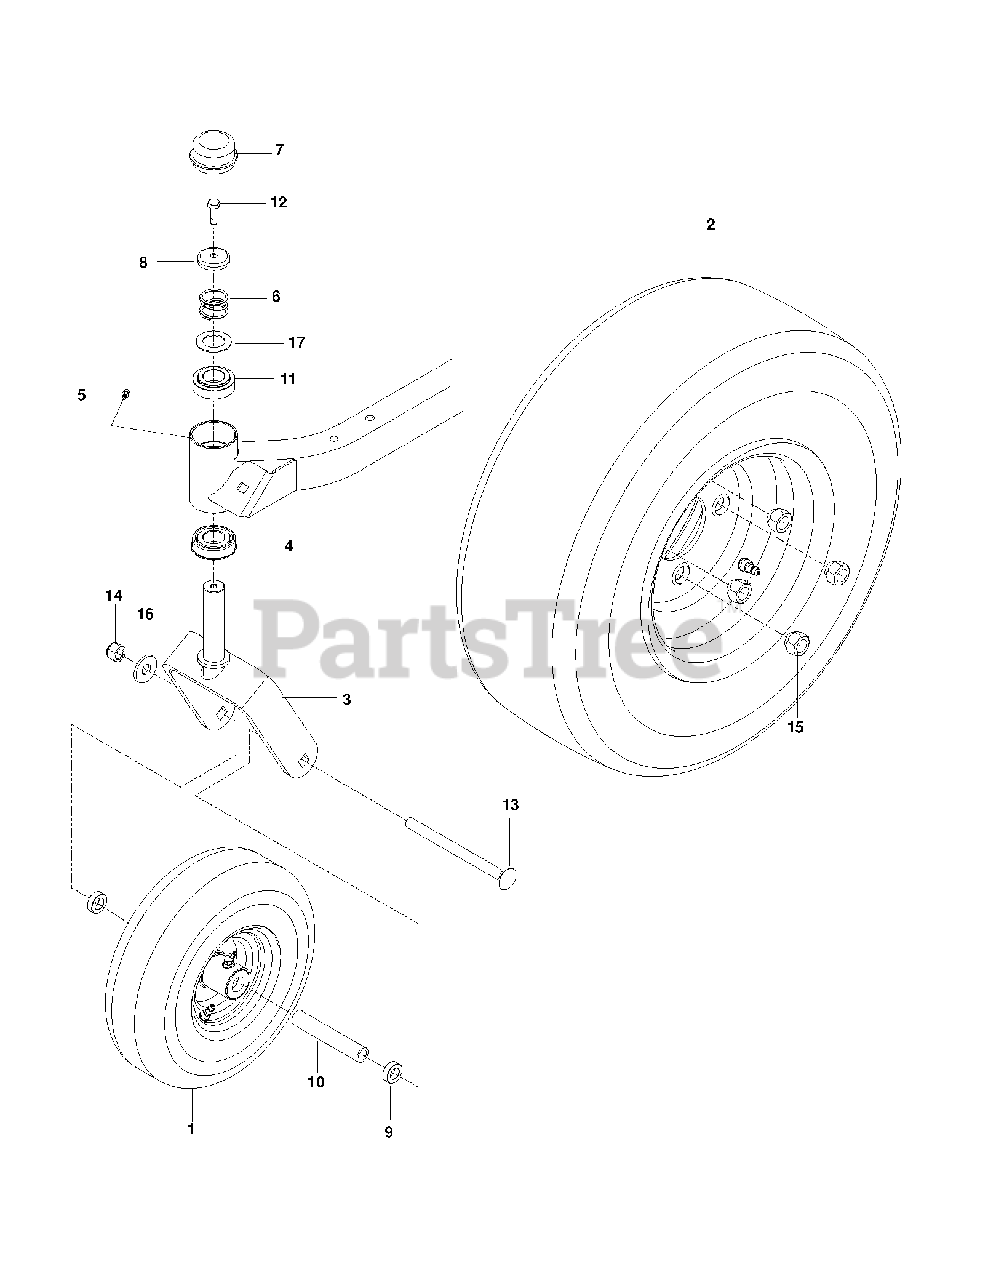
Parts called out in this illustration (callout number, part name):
1	TIRE, CASTER, COMPLETE
3	CASTER DK BLUE
4	BEARING FLANGED
5	ZERK, 3/16, DRIVE IN
6	SPRING, CASTER
7	GREASE CAP
8	CASTER.PLUG
9	SPACER, 5/16"
11	BUSHING, CASTER
12	5/16-18X1 HHB G5W/NY
13	RHSNB 1/2-13 X 6.50 GR2 ZD
14	NUT 1/2-13 HEX CNTRLK GR 5 ZD
15	LUG NUT 1/2F
16	WASH USS FLAT 1/2
17	WASHER, 1.025 ID X 1.64
